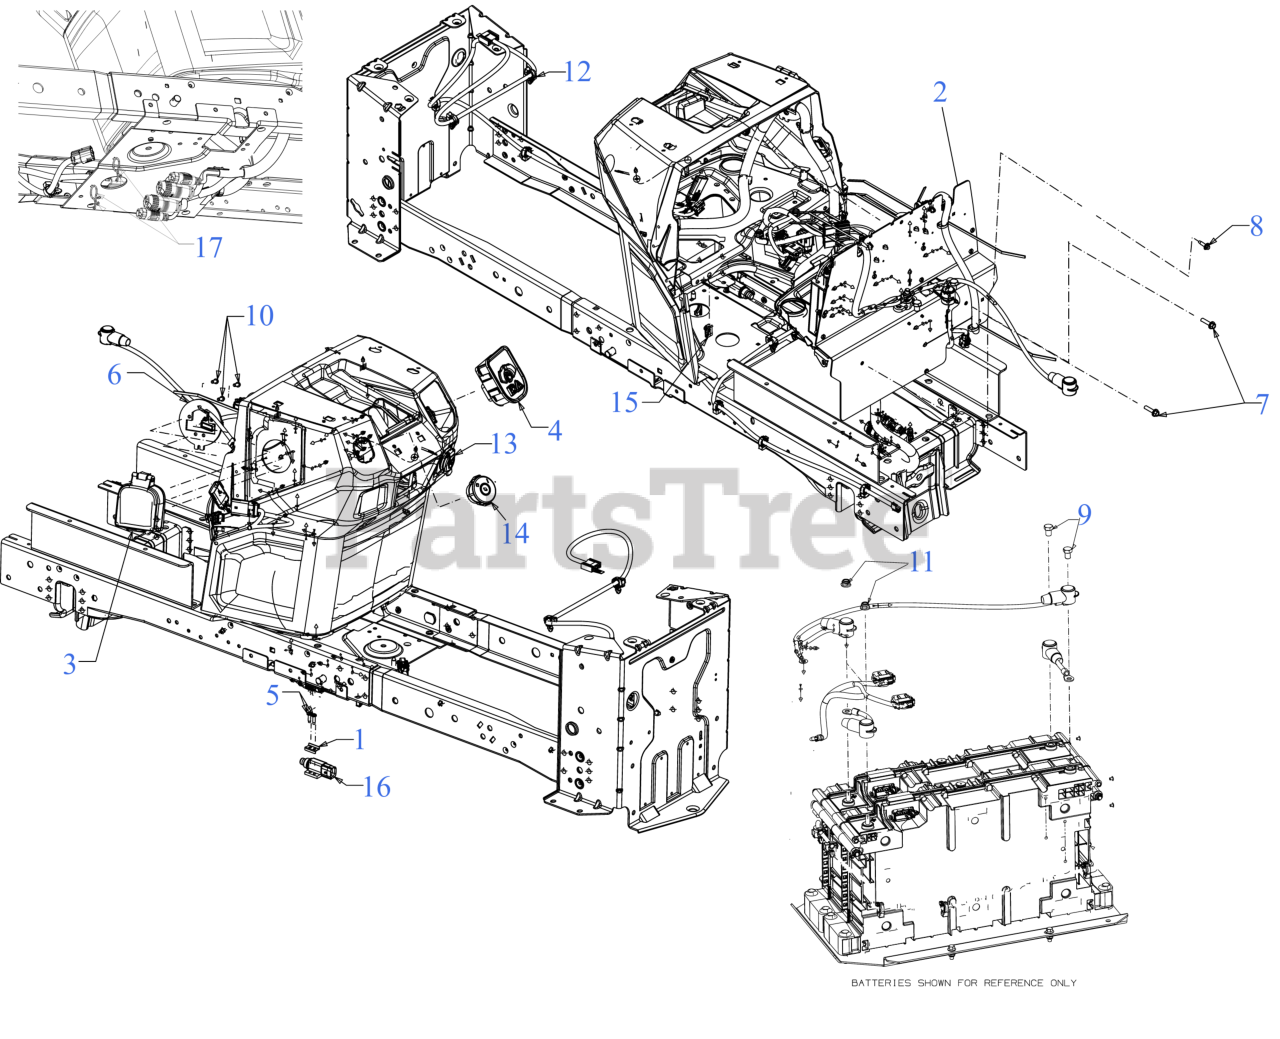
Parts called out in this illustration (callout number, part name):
1	PLATE-SWITCH
2	MOTOR CONTROL PANEL
3	LI-ION CHARGE PORT ASSEMBLY
4	VCM MODULE
6	CHARGE PORT MOUNTING PLATE
7	SCREW 1/4-20 x 1.0
8	SCREW 1/4-10 x .750
9	SCREW 3/8-24 x .50" GR5 STD
10	SCREW #12-16 x .625
11	FLANGE LOCK NUT 5/16-18
12	HARNESS (VCM HPD BATTERY)
13	USB RECEPTACLE (12V W/JUMPER)
14	KEY SWITCH (2 POSITION)
15	U-CLIP NUT
16	SEALED PLUNGER SWITCH
17	TWIST LOCK CLIP
